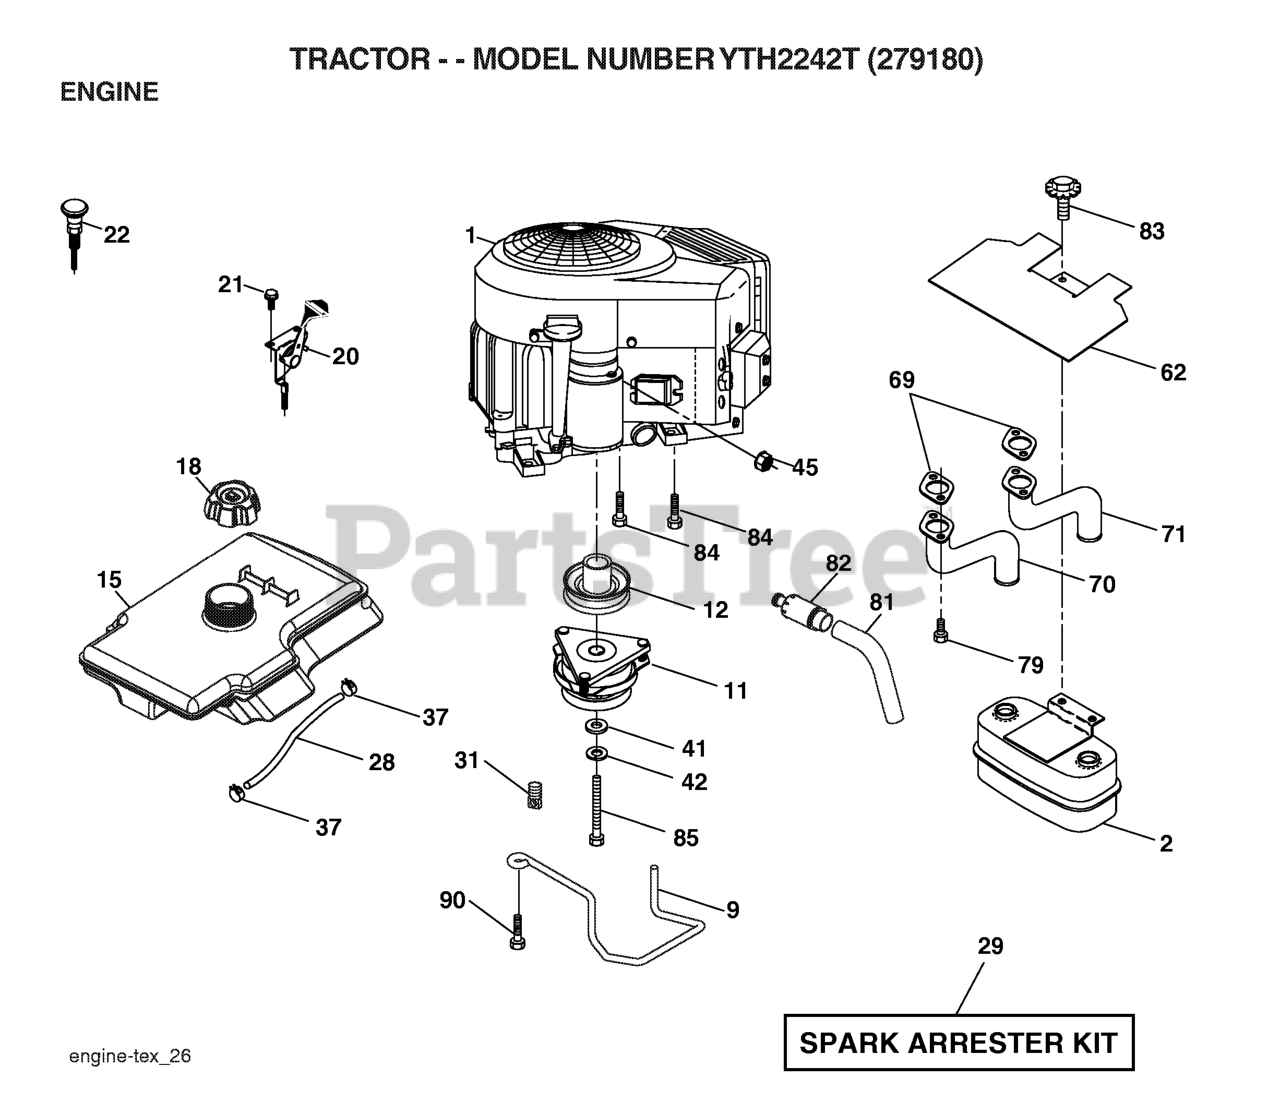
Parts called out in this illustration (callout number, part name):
2	MUFFLER.TWIN.CYL.LOW.TONE
9	KEEPER.BELT.ENGINE.3.25 (3 2)
11	RB.CLUTCH.OGURA.4.4.PD
12	PULLEY.ASM.ENG.OGURA.3
15	TANK.FUEL.2.5.RR.MNT.H
18	CAP.ASM.FUEL.TANK.3"BL
20	THROTTLE CABLE
21	SCREW
22	CONTROL.CHOKE.ERGO.PUSH-IN.BLA
28	LINE.FUEL.64"REAR.EMIS
29	KIT.SPARK ARRESTOR 794945 B&S
37	HOSE CLAMP
42	LOCKWASHER
45	NUT
62	RP SHIELD HEAT MUFFLER
69	GASKET.MUFFLER
70	RP.EXHAUST.TUBE.LH.BS/TWIN
71	EXHAUST.TUBE.RH.BS/TWIN
79	SCREW.SOCKET.HEAD.5/16-18
81	TUBE, DRAIN OIL ASM.
82	PLUG DRAIN OIL EASY
83	BOLT.5/16-18UNCX1.W/SEMS.BLK
84	SCREW.3/8-16
85	BOLT HEX 7/16-20X4-1/4"
90	SCREW 3/8-16X1
